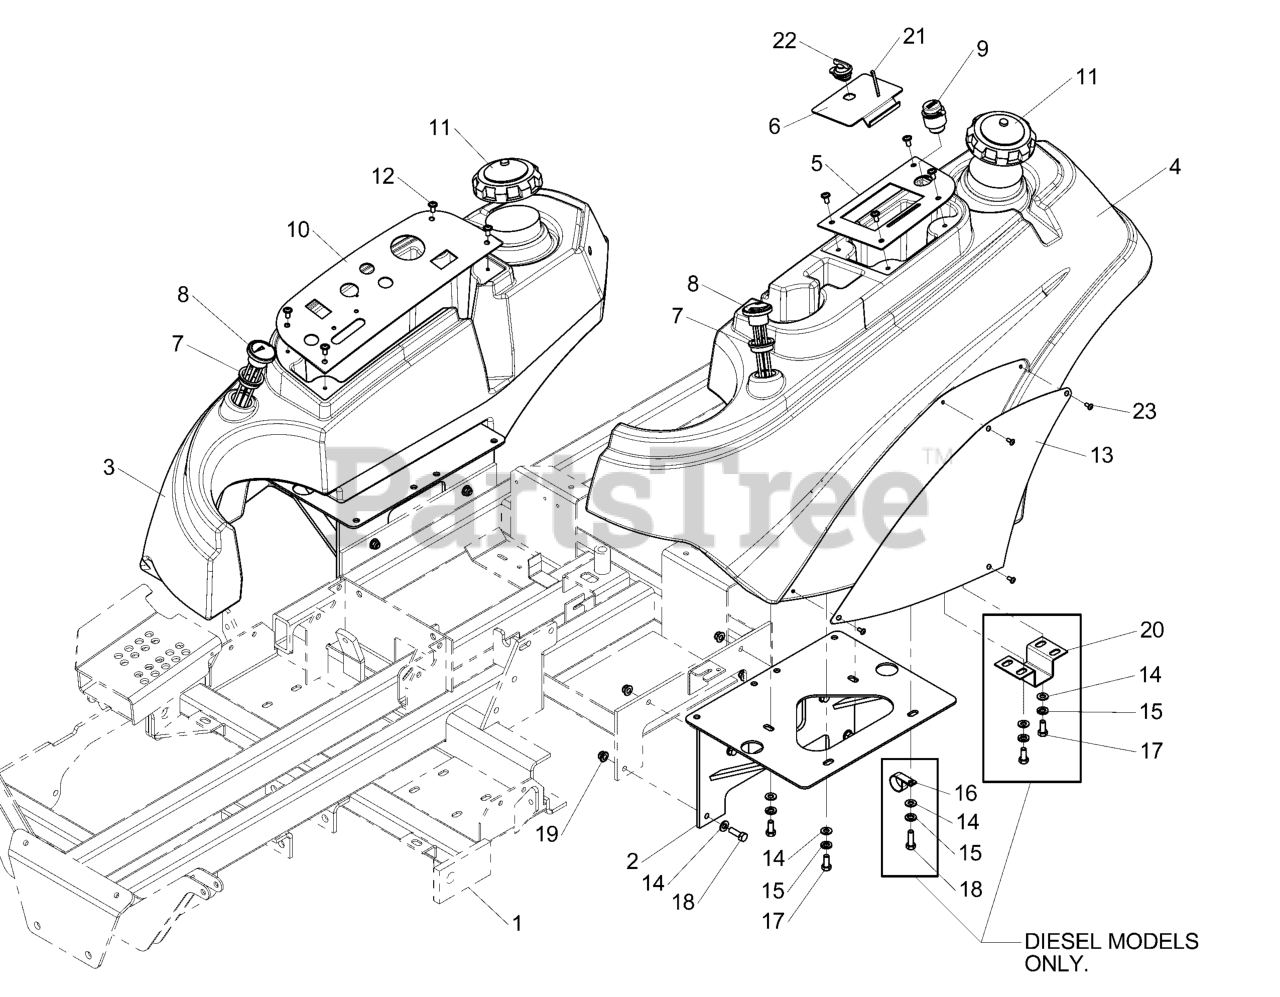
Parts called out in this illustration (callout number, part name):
1	MAIN FRAME
2	WELD, FUEL TANK
3	TANK, FUEL, DIESEL, RH
3	FUEL TANK, GAS, RH
4	TANK, FUEL, DIESEL, LH
4	FUEL TANK, GAS, LH
5	PANEL, CONTROL - LH
6	COVER, CONTROL PANEL
7	GROMMET
8	GAUGE, FUEL, 12
9	POWER, OUTLET - 12 VOLT
10	CONTROL PANEL
11	CAP, FUEL TANK (DIESEL)
11	CAP, GASOLINE, VENTED
12	SCREW, 1/4-20 X 1/2" ALLEN BH
13	PLATE, BADGE, IS4500Z
14	WASHER, 5/16" SAE
15	WASHER, 5/16 LOCK CZ
16	CLAMP, VINYL
17	BOLT, 5/16-18 X 3/4 GD5
18	BOLT, 5/16-18 X 1" GD5 YZ
19	NUT, 5/16-18 HEX NYLOCK FLANGE
20	GUARD, FUEL TANK SHUT-OFF
21	PIN, COTTER, 1/8 X 1-1/4
22	LATCH, CONTROL PANEL
23	SCREW, #10-24 X 3/8" ALLEN BHBZ
